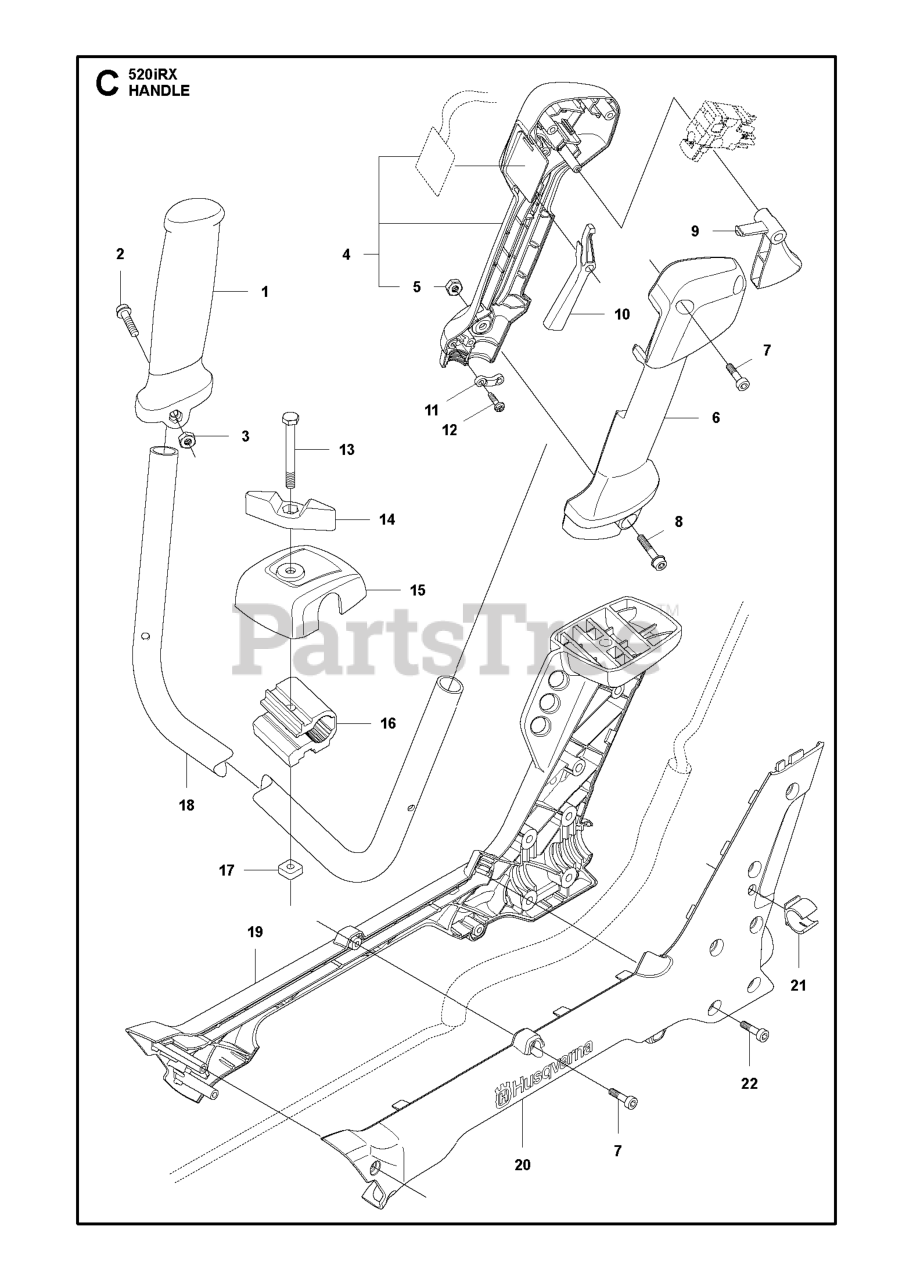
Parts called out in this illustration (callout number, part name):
7	SCREW
8	SCREW
15	COVER HANDLE BAR
18	HANDLEBAR MACHINED
